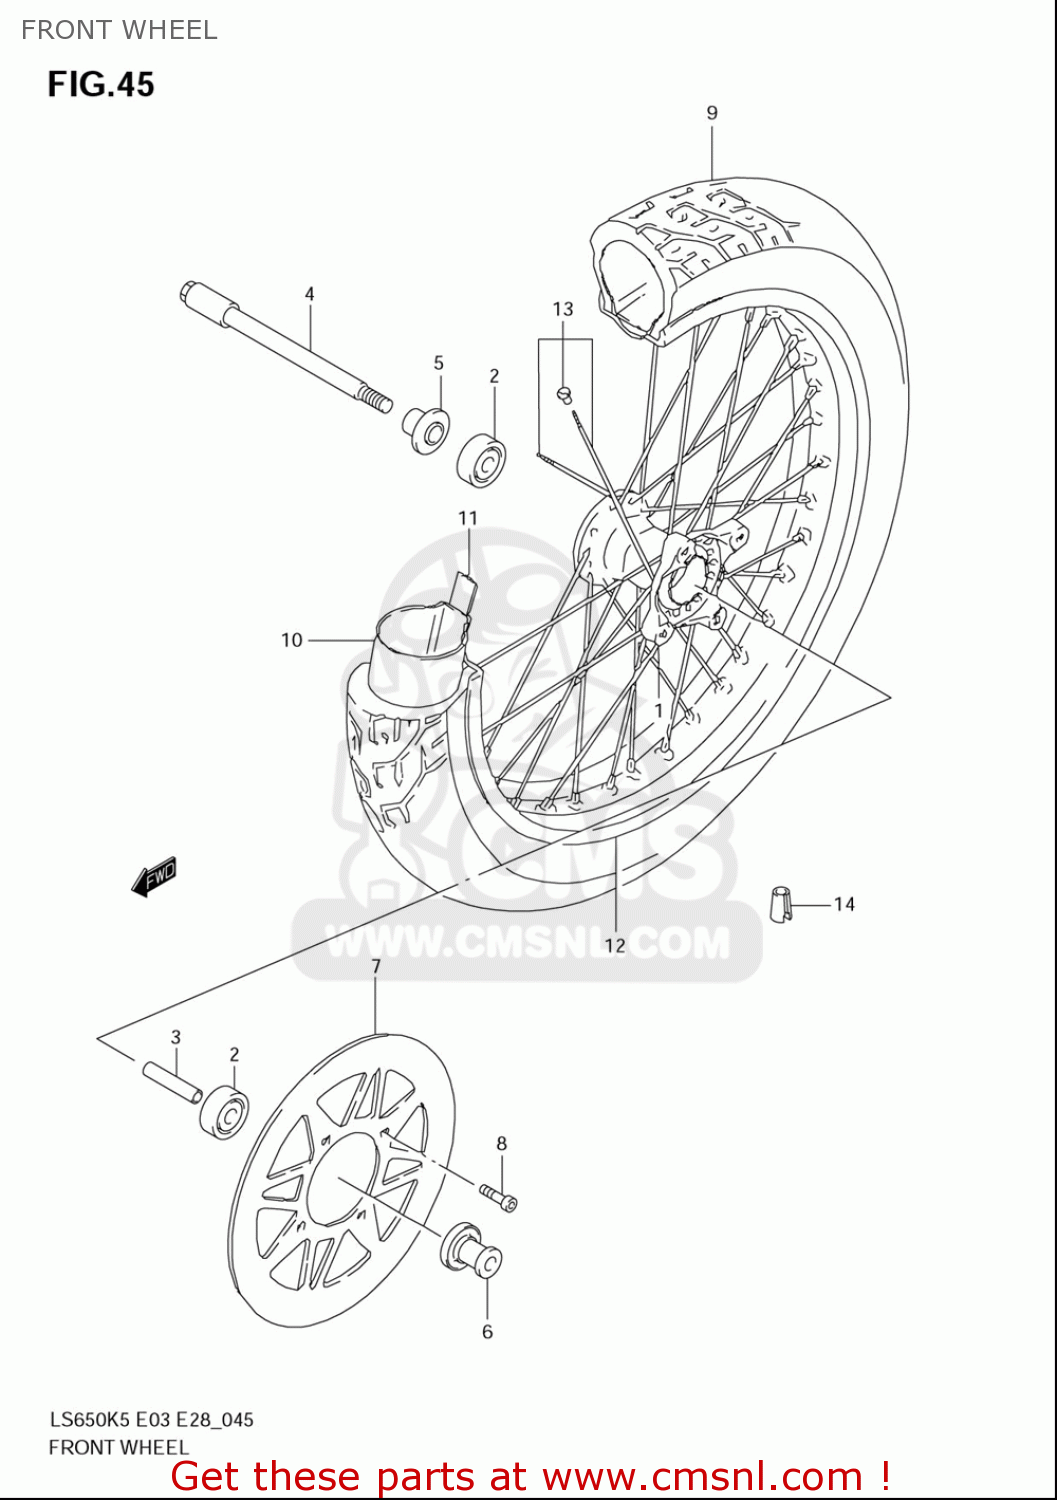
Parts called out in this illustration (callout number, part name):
1	HUB,FR WHEEL
2	B1 15X42X13 BEA
3	SPACER(15.3X21.7X56)
4	AXLE,FR
5	SPACER,FR AXLE,R
6	SPACER,FR AXLE,L
7	DISC,FR BRAKE
8	BOLT(8X25.5)
9	TIRE,FR(100/90-19 57H)
10	TUBE ASSEMBLY,WHEEL,INNER
11	PROTECTOR,WHL INR TUBE
12	RIM,FR WHEEL WM(2.15X19)
13	SPOKE SET,FR WHEEL
14	BALANCER,WHEEL(15G)
